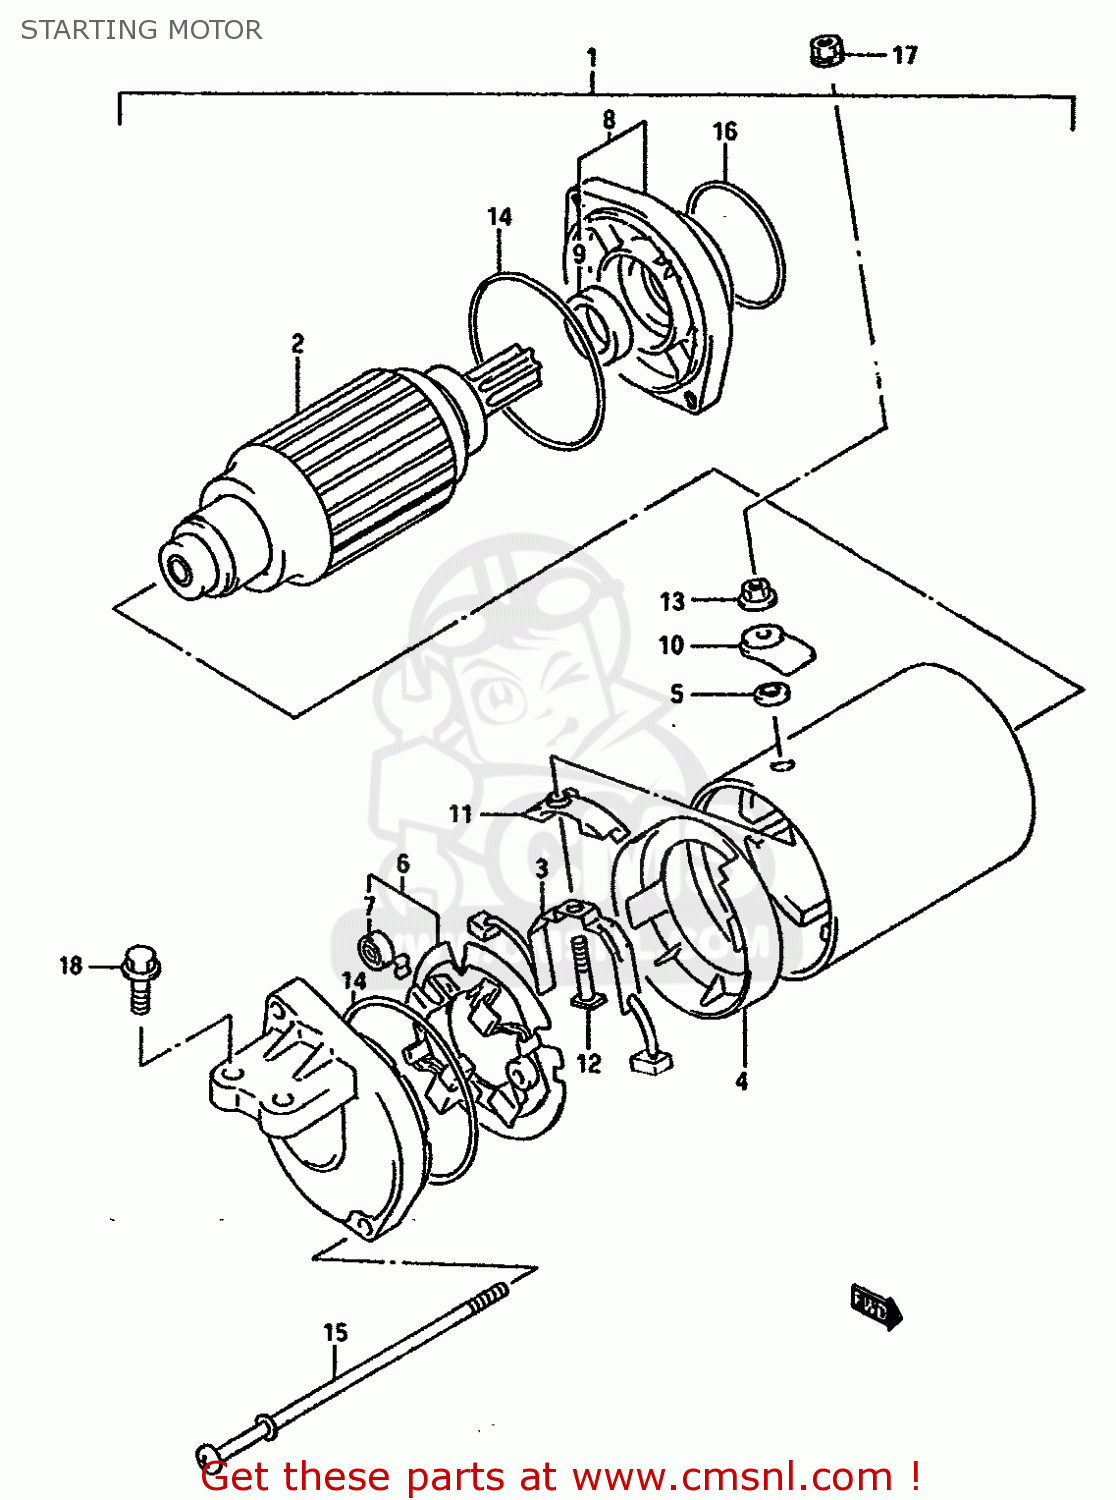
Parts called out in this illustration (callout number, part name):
1	MOTOR,STARTING
2	ARMATURE
3	TERMINAL SET,BRUSH
4	INSULATOR
5	GASKET (NAS)
6	HOLDER SET,BRUSH(-)
7	SPRING
8	BRACKET SET
9	SEAL,OIL
10	BUSHING
11	BUSHING
12	BOLT
13	NUT
14	O RING
15	BOLT
16	O-RING (D:2.0)
17	NUT
18	BOLT
